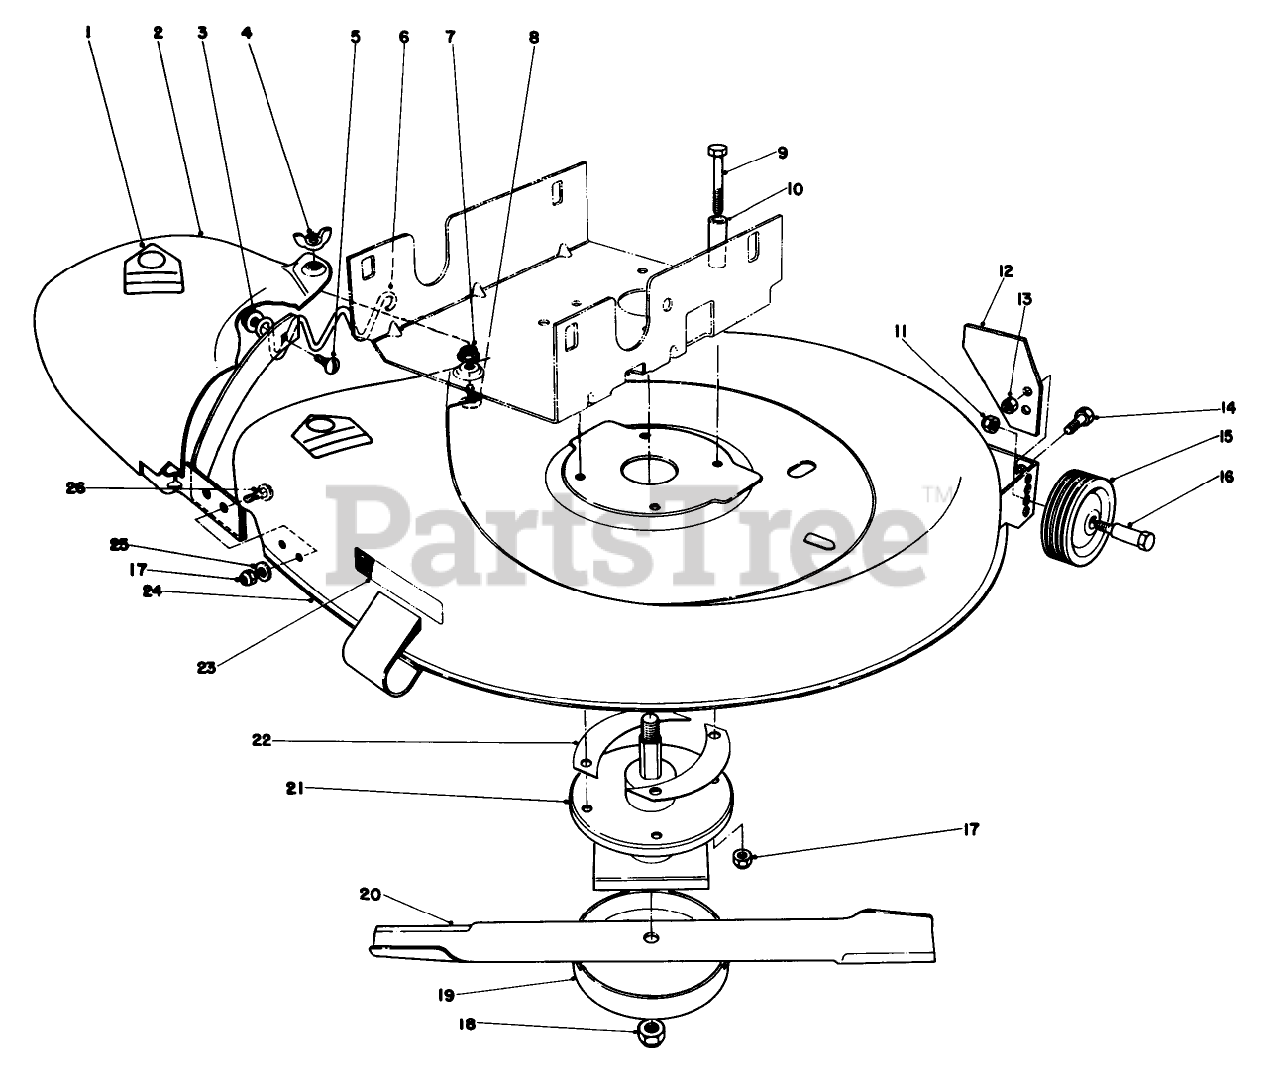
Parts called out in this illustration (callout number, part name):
3	NUT-LOCK, HHF
9	SCREW-HH
13	NUT-LOCK, CONE
14	SCREW-HH
17	NUT-LOCK, NI
18	NUT-SPECIAL
25	WASHER-FLAT
26	BOLT-CARR
